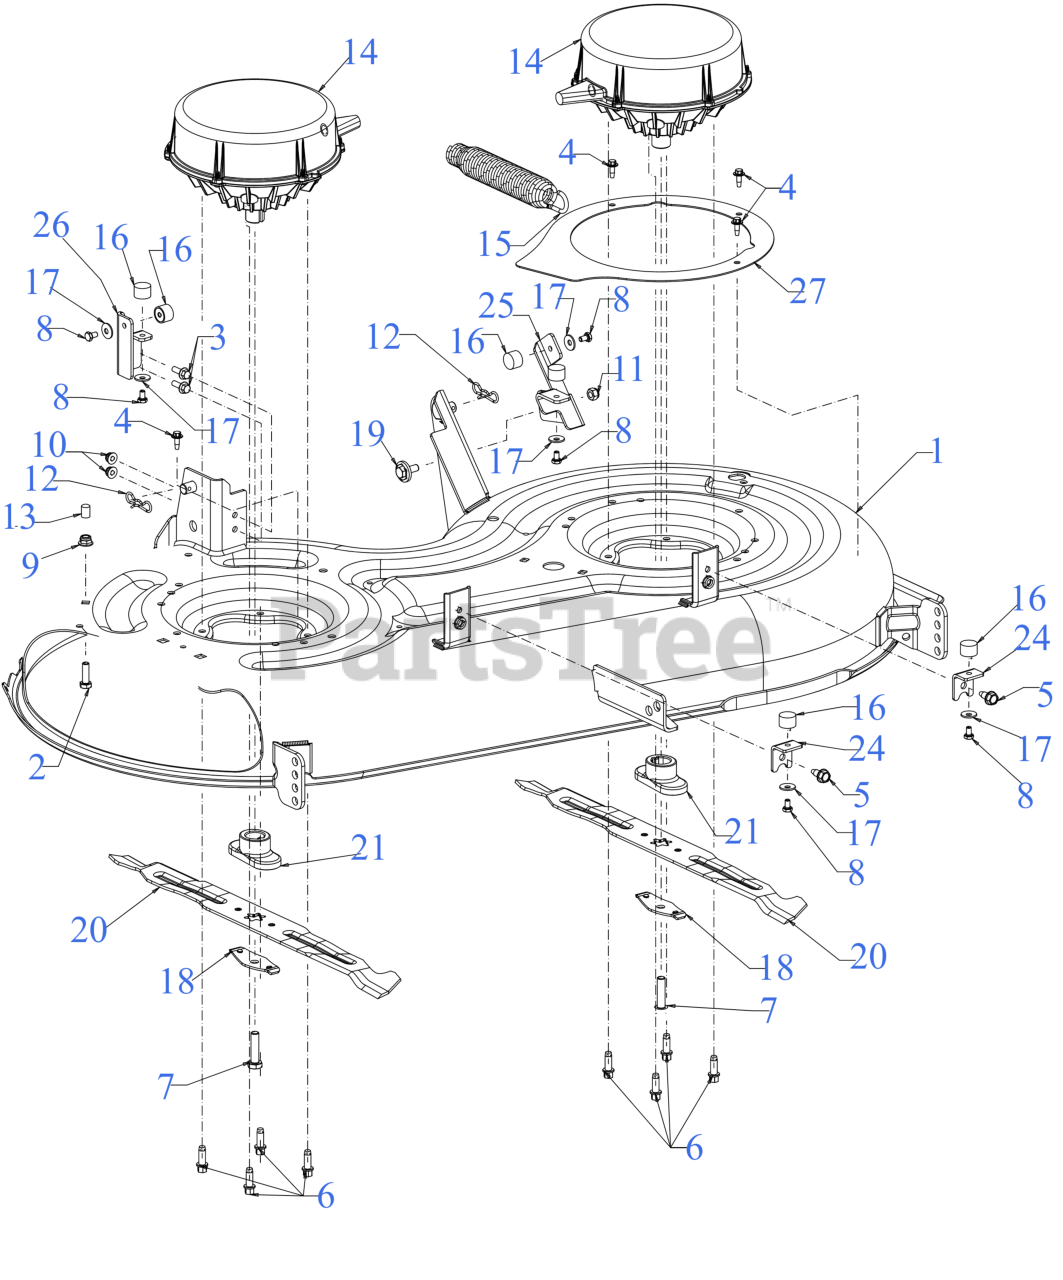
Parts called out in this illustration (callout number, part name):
1	42" DECK
2	SCREW 5/16-18 x 1.0 GR5
3	SCREW 1/4-20 x .75 GR5
4	SCREW M6-1 x .625
5	SCREW M8-1.25 x .750
6	SCREW 5/16-18 x .875
7	SCREW 3/8-24 x 1.50 GR8
8	SCREW M6-1.0X10MM GR8.8
9	FLANGE LOCK NUT 5/16-18
10	FLANGE LOCK NUT
11	HEX NUT
12	BOW TIE COTTER PIN
13	VINYL CAP
14	48V ELECTRIC DECK MOTOR
15	LIFT ASSIST SPRING (SMALL)
16	BUMPER
17	SPRING WASHER BELL
18	BLADE BELL SUPPORT
19	SHOULDER SCREW
20	21.18" MULCH BLADE
21	BLADE ADAPTER (#6 x 1.19 W/STAR)
24	UPSTOP BRACKET
25	UPSTOP BRACKET (LH)
26	UPSTOP BRACKET (RH)
27	DECK COVER BRACKET
